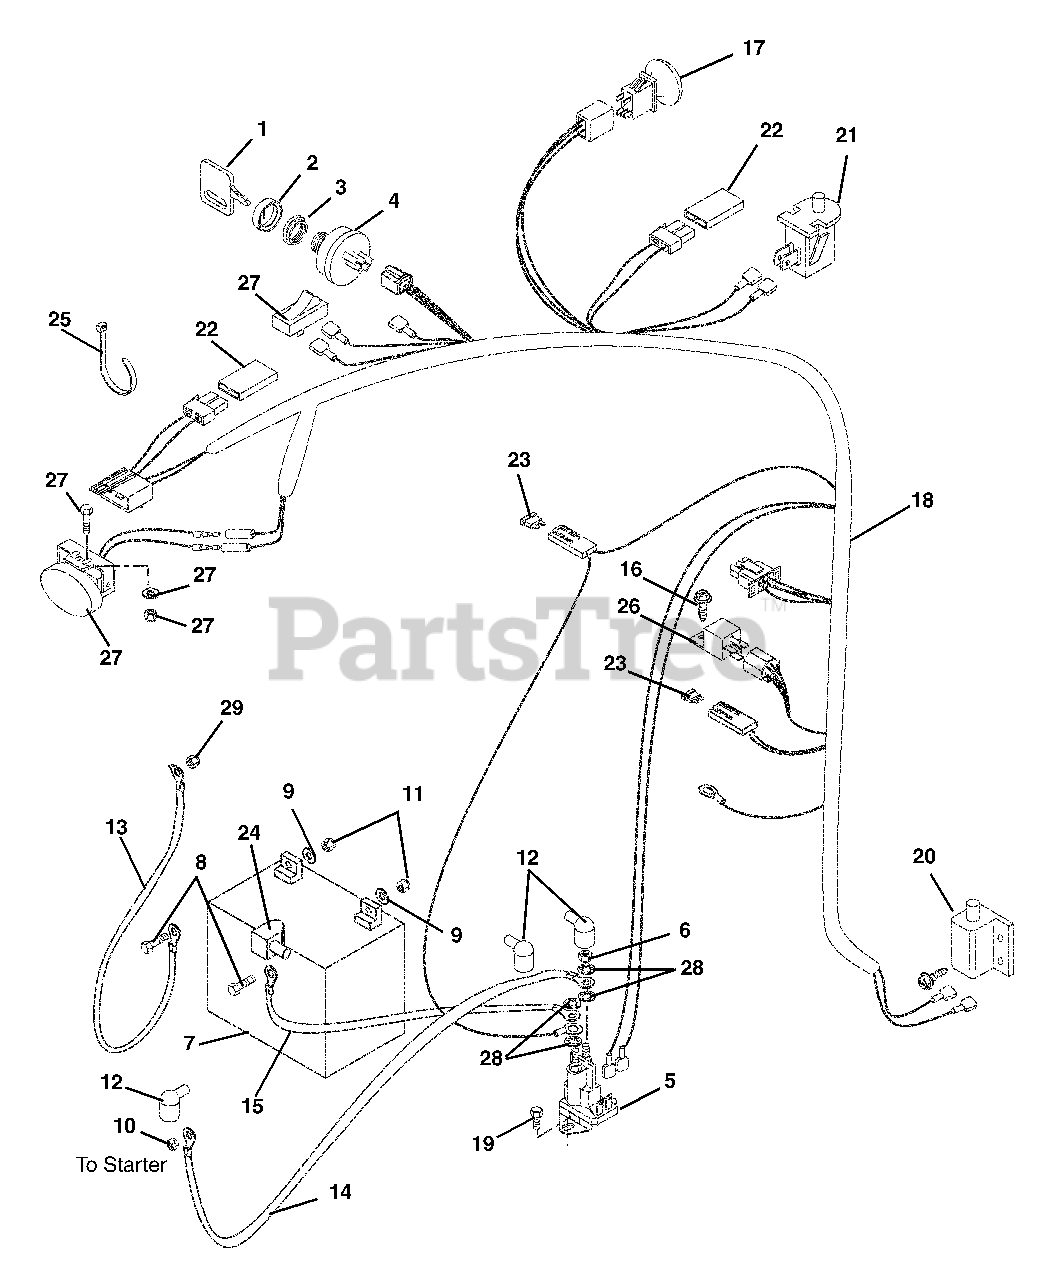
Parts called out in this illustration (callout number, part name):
1	KEY -W/CAP
2	CAP - IGNITION SWITCH
3	NUT- PANEL .562-24 GRECO
4	SWITCH KEY 5Y463A ALT GRDNG
5	SOLENOID
6	NUT-JAM .31-24 YWZC
8	@BLT-HEX .25-20X.75 GR5 YWZC
9	@WSHR-LK .25X.062 REG YWZC
10	@NUT-SPNLK-FLG .25-20 YWZC
11	@NUT-HEX .25-20 YWZC
12	BOOT, EYELET TERMINAL
13	CBL,NEGATIVE BATTERY 20.00
14	STARTER CABLE 13"
15	STARTER CABLE 16"
16	SCR-TAP 10-24X.375 TORX PHD YZ
17	SWITCH, CLUTCH
18	HARNESS-ZOOM SPORT 6PIN
19	@SCR-TAP .25-20X.37 HWH YWZ TR
20	SWITCH- SINGLE POLE N.O.
21	SWITCH- SNAP MTG N.O.
22	DIODE, CONNECTOR SHELL
23	FUSE-25 AMP ATC TYPE
24	INSULATOR
25	CABLE TIE LG 5-1/2
26	RELAY
27	KIT-LIGHT RER/SPORT
28	WSHR-LOCK INT .31 YWZC
29	NUT-LK-TOP-FLG .31-18 BLKZC
